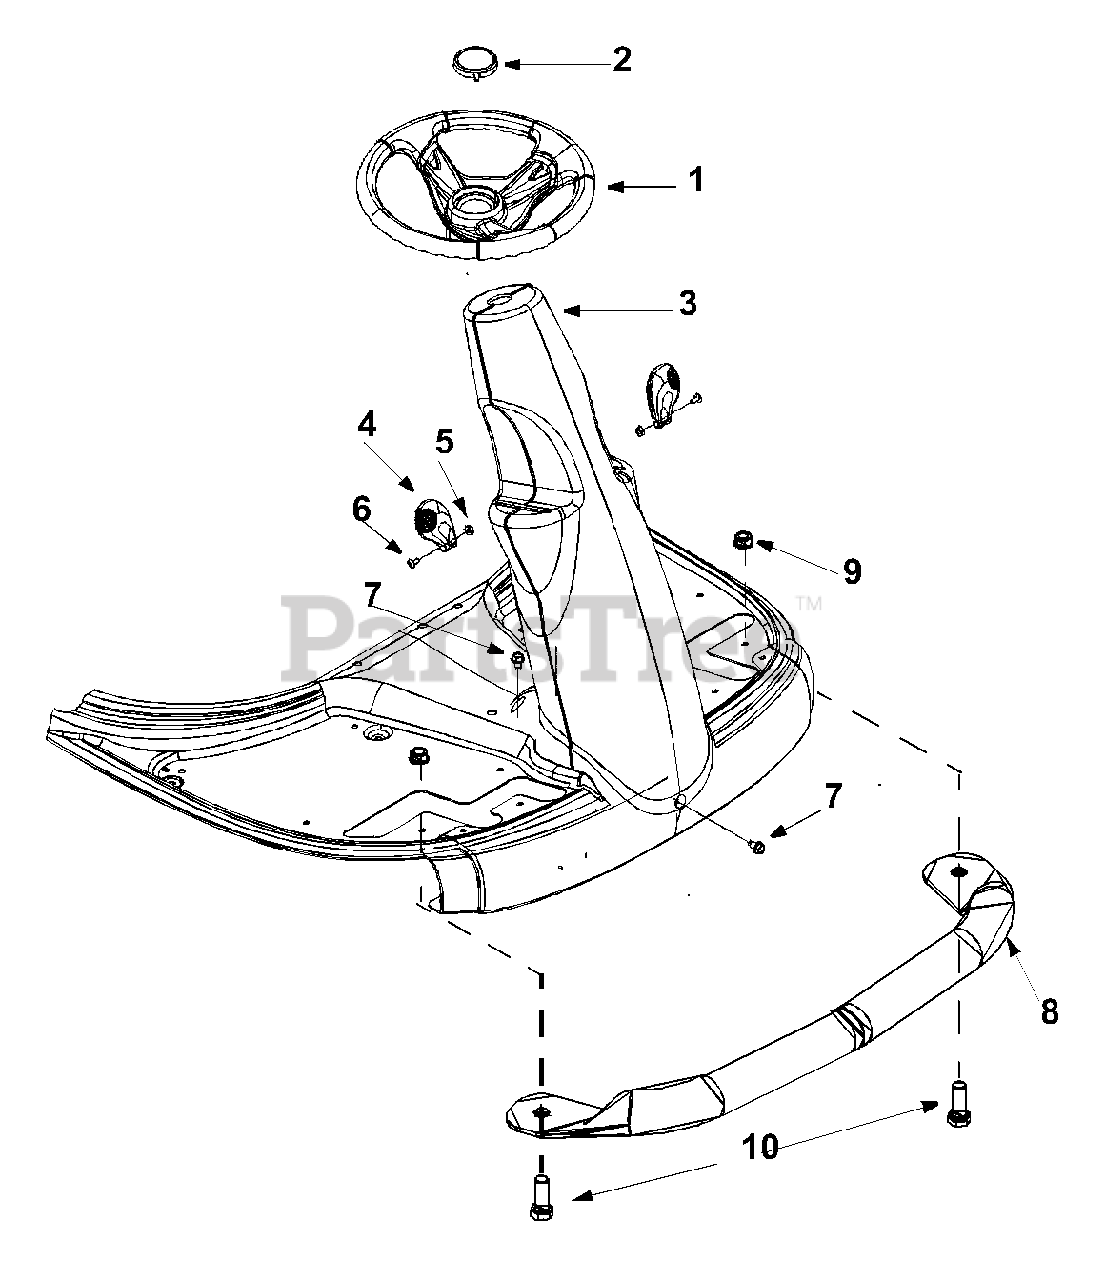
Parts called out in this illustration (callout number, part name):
1	Steering Wheel: 3 Spoke
2	Steering Wheel Cap
3	Steering Column: Black
4	Control Knob
5	Hex Nut 8-32
6	Pan Head Machine Screw #8-32
7	Hex Screw TT 1/4-20 x .50"
9	Lock Nut
10	Hex Screw 3/8-16 x 1.0"
